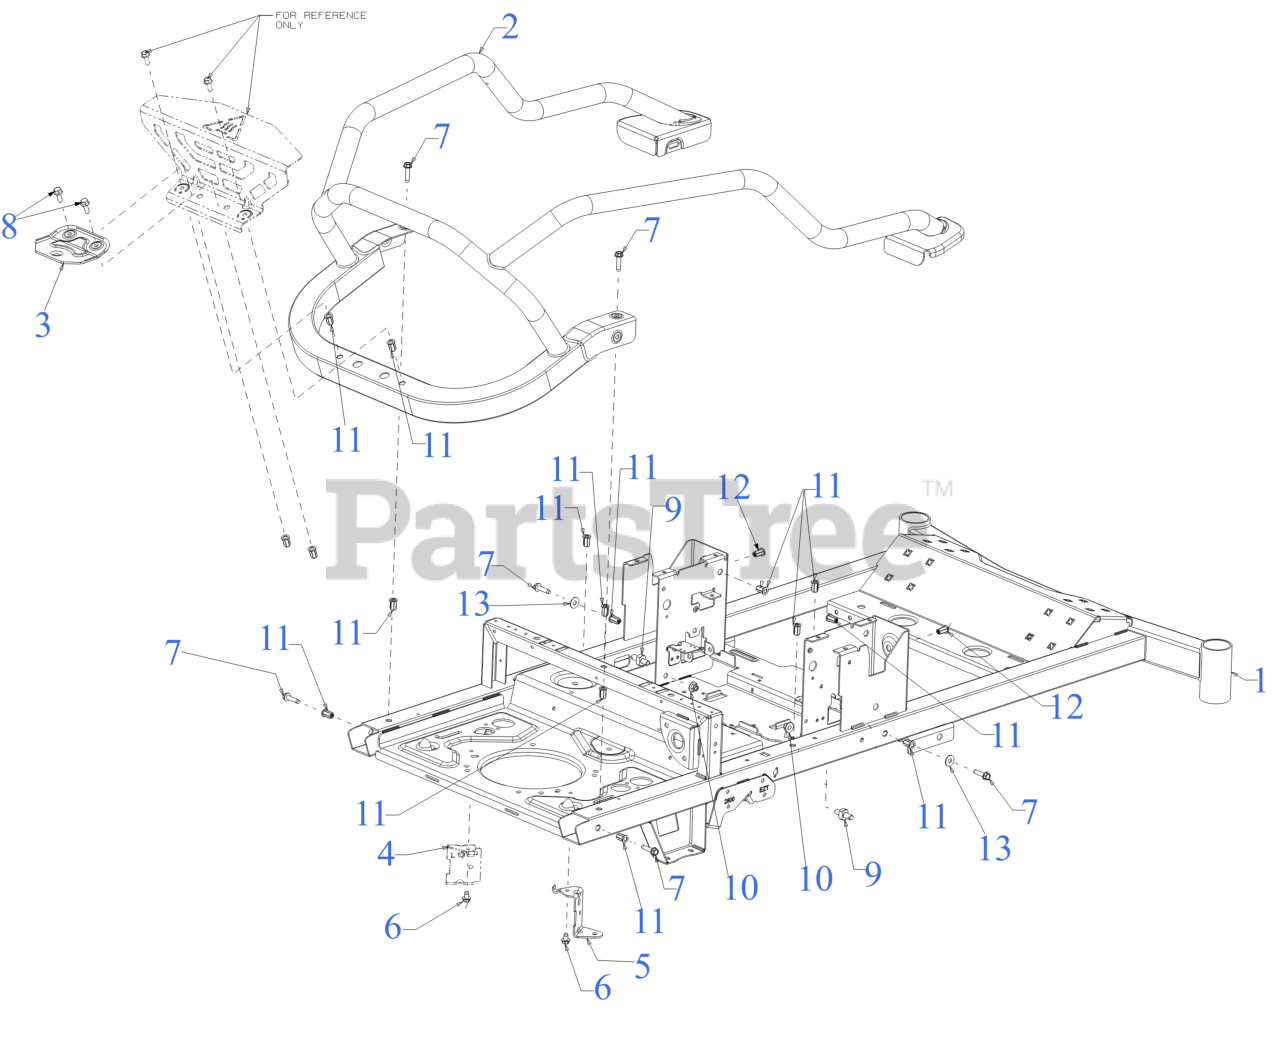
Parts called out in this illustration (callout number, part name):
1	FRAME
2	UPPER FRAME
3	HITCH PLATE
4	TRANSMISSON MOUNT SUPPORT (LH)
5	TRANSMISSON MOUNT SUPPORT (RH)
6	SCREW 5/16-18 x .500
7	SCREW 5/16-18 x 1.25
8	SCREW 5/16-18 x .875 GR5 HXFLG HD
9	SHOULDER STUD
11	NUT RIVET 5/16-18
12	NUT RIVET 5/16-18
13	FLAT WASHER
